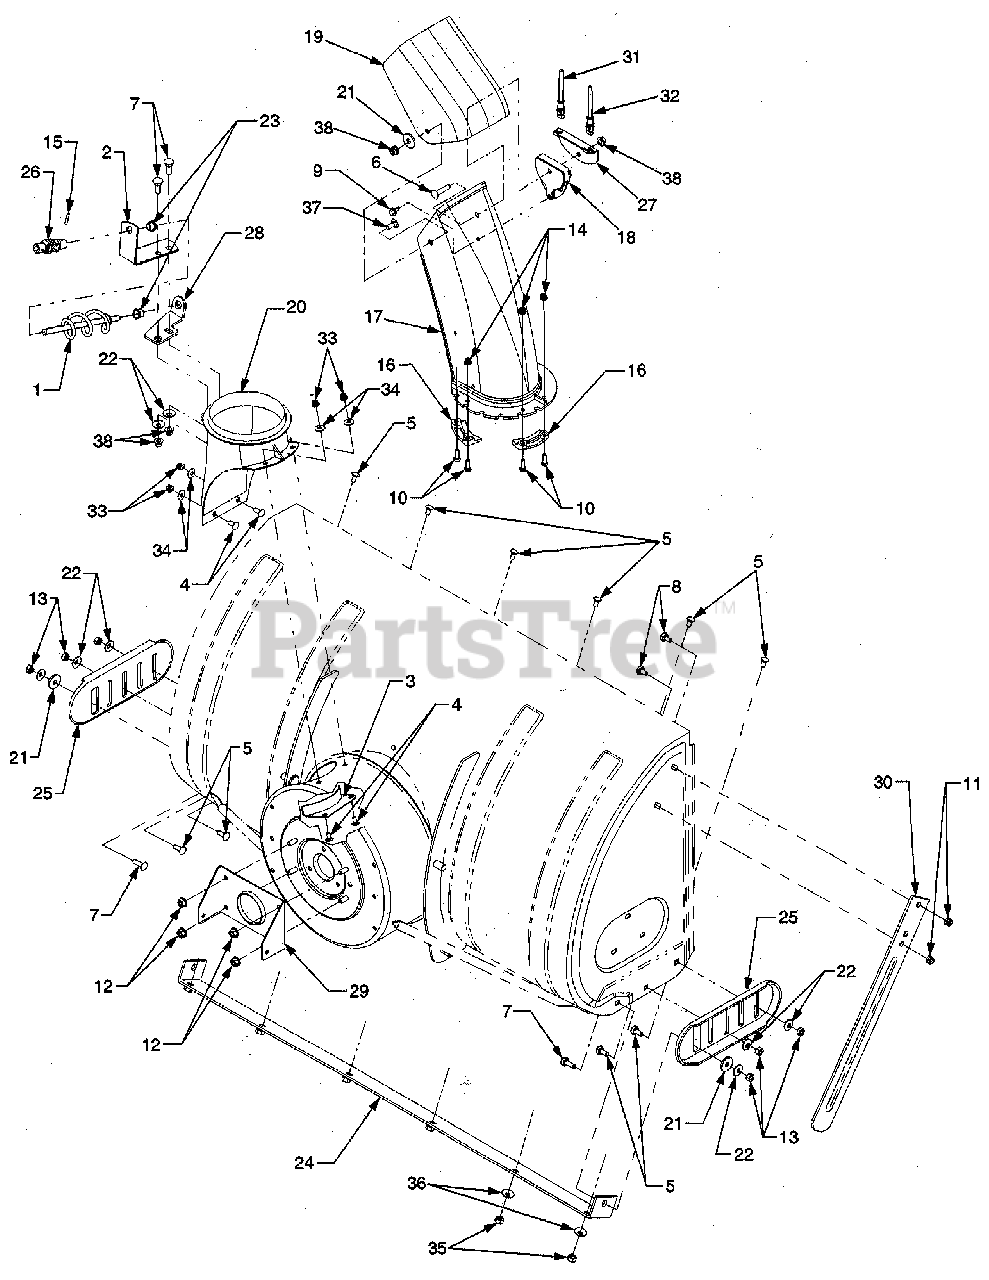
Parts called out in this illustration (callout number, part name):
1	Chute Crank
2	Bracket, Chute Crank
3	Plate, Chute Reinforcement
4	Bolt, Carriage. 1/4-20 x . 5. Mfg. Code 1I040G and before
5	Bolt, Carriage. 511 6-1 8 x . 62
6	Bolt, Carriage. 5116-1 8 x 1.5
7	Bolt, Carriage. 5116-1 8 x 1.0
8	Bolt, Carriage. 511 6-1 8 x . 75
9	Screw, Hex Wash . Hd Tapp 1/4-14 x .625
10	Screw, Hex Cap 1/4-20 x .75 GR5
11	Nut, Hex Insert Lock. 5/16-18
12	Nut, Hex Flange Lock. 5/16-18 GR5
13	Nut, Hex. 5/16-18 GR5
14	Nut, Hx Insert Flange Lk. 1/4-20. Replaces 712-3027
15	Pin, Spirol. 118 x . 812
16	Keeper, Chute Flange
17	Chute, Lower Discharge
18	Guide, Cable
19	Chute, Upper Discharge
20	Adapter, Discharge Chute
21	Washer, Flat. . 344 x 1 . 125 x . 12
22	Washer, Bell. . 34 x . 872 x . 06
23	Bushing, Plastic
24	Plate, Shave
26	Block Assembly, Joint
27	Bracket, Cable
28	Bracket, Chute Crank
29	Bracket, Box Mounting
30	Guide, Blade
31	Cable, Chute Control
32	Cable, Chute Control w/Clip
33	Nut, Hx Insert Flange Lk. 1/4-20. Replaces 712-3027 & 712-0324
34	Washer, Flat. .25 x . 625 x . 052. Mfg. Code 1I050G and after
35	Nut, Hex Flange Lock. 5/16-1 8 GR5. Mfg. Code 1E301G and before
36	Washer, Bell, .34 x . 872 x . 06. Mfg. Code 1E311G and after
37	Screw, Carriage. 5/16-18 x 1.0. Replaces 710-0451 or 710-0276
38	Nut, Hx Insert Flange Lk. 5/16-18. Replaces 712-3010 & 712-0429
